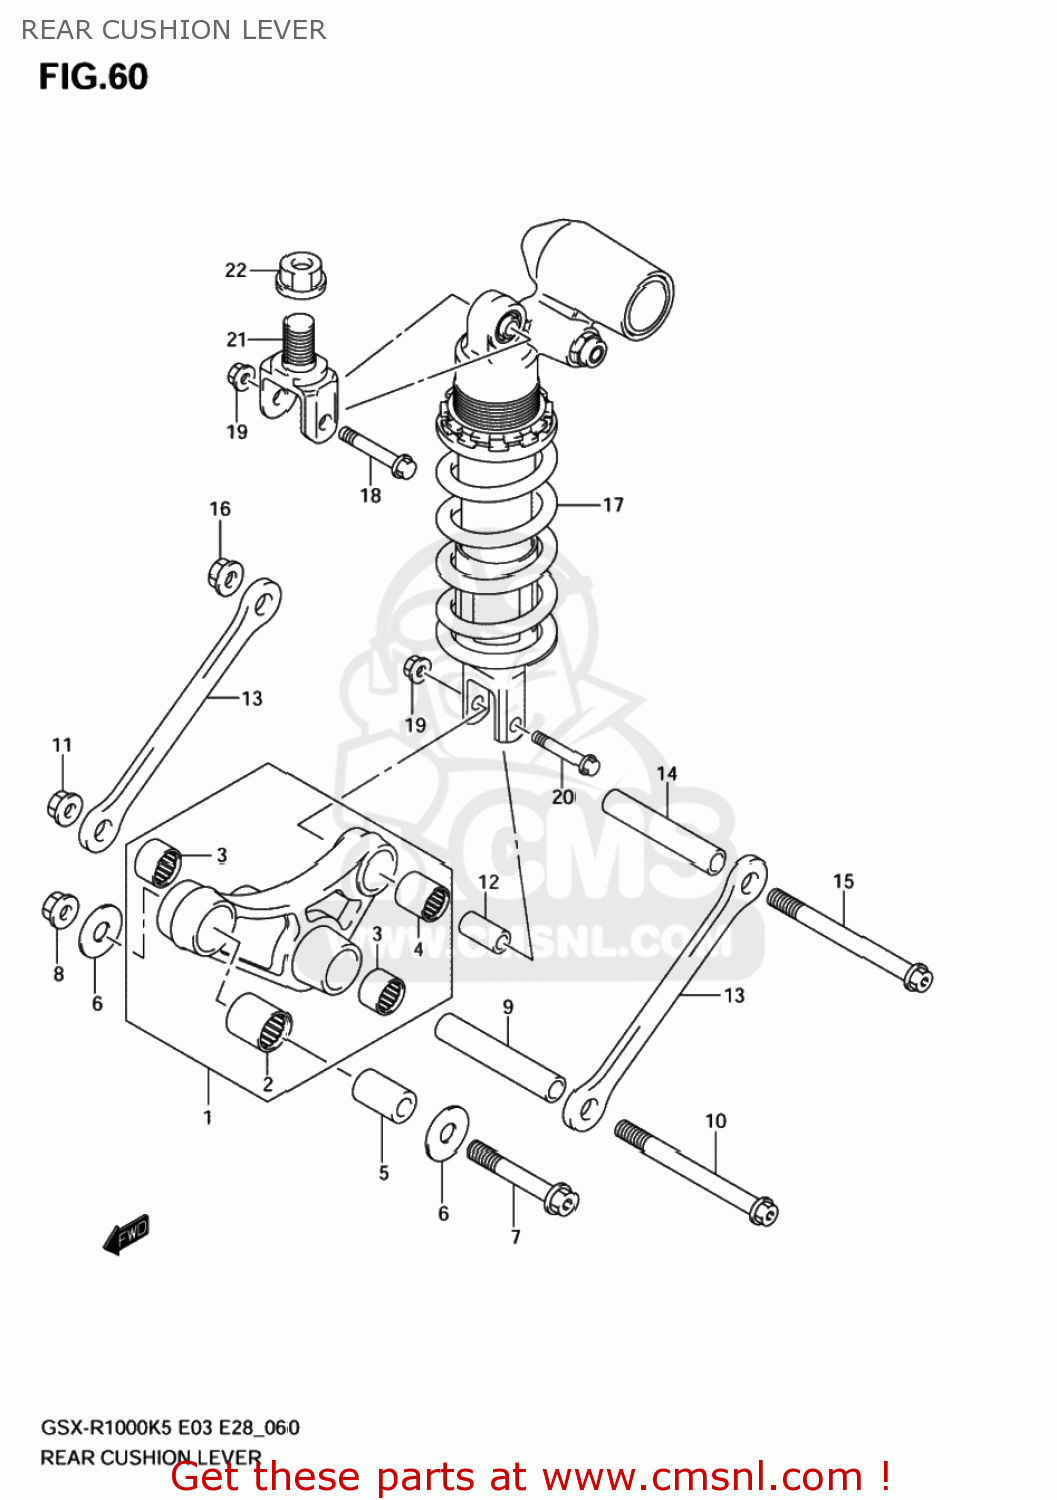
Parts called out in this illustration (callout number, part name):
1	LEVER SET,RR CUSHION
2	BEARING(20X27X30)
3	BEARING(17X24X20)
4	BEARING(17X24X26)
5	SPACER,RR CUSHION LEVER FR
6	WASHER(12X34X1)
7	BOLT,RR CUSHION LEVER FR
8	NUT
9	SPACER,RR CUSHION LEVER CTR
10	BOLT,RR CUSHION LEVER CTR
11	NUT
12	SPACER,RR CUSHION LEVER
13	ROD,RR CUSHION
14	SPACER,RR CUSHION LEVER CTR
15	BOLT,RR CUSHION LEVER CTR
16	NUT
17	ABSORBER ASSY,RR SHOCK
18	BOLT(10X55)
19	NUT
20	BOLT(10X55)
21	BRACKET,RR SHOCK ABSORBER UPR
22	NUT
